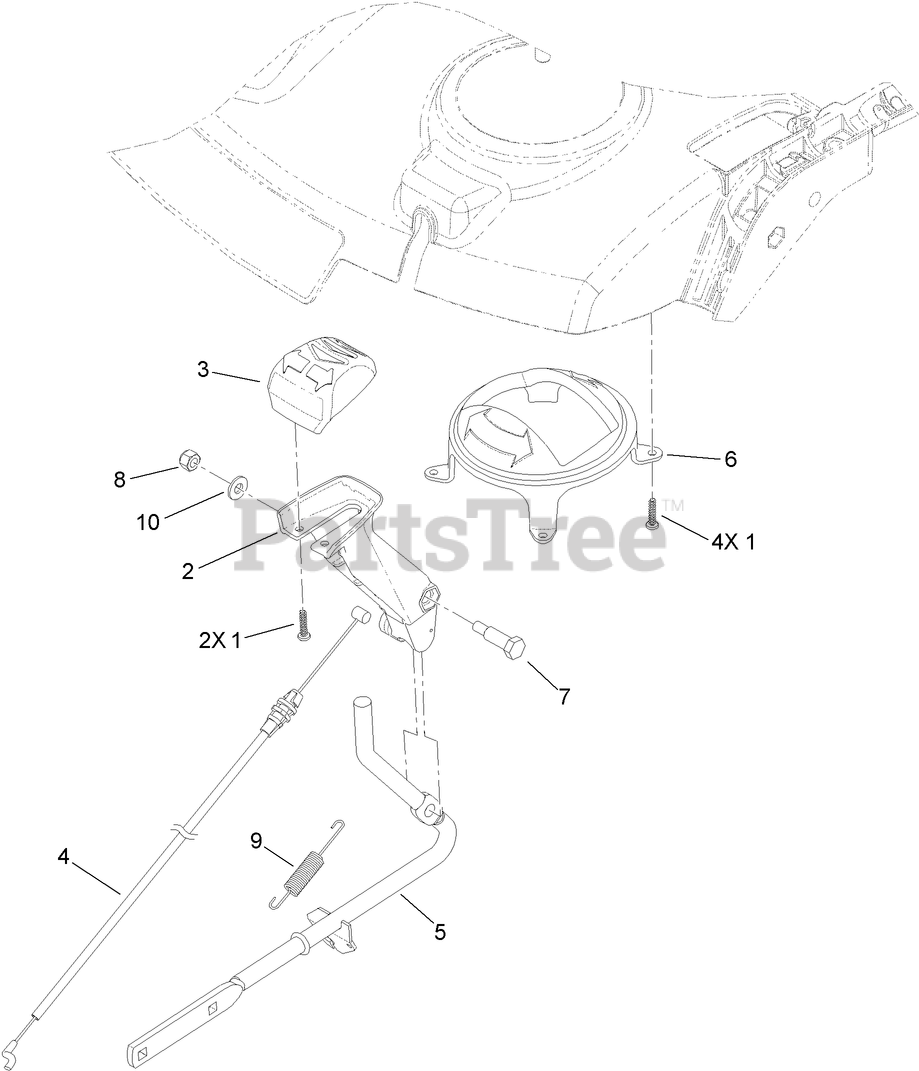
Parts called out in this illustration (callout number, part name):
1	SCREW-PPH
2	LEVER-CONTROL, CHUTE
3	CAP-LEVER, CHUTE CONTROL
4	CABLE-RELEASE, CHUTE
5	CHUTE ROD ASM
6	INSERT-LEVER, QUICK
7	SCREW-SHOULDER
8	NUT-LOCK, NI
9	SPRING-RETURN, LEVER
10	WASHER-FLAT
